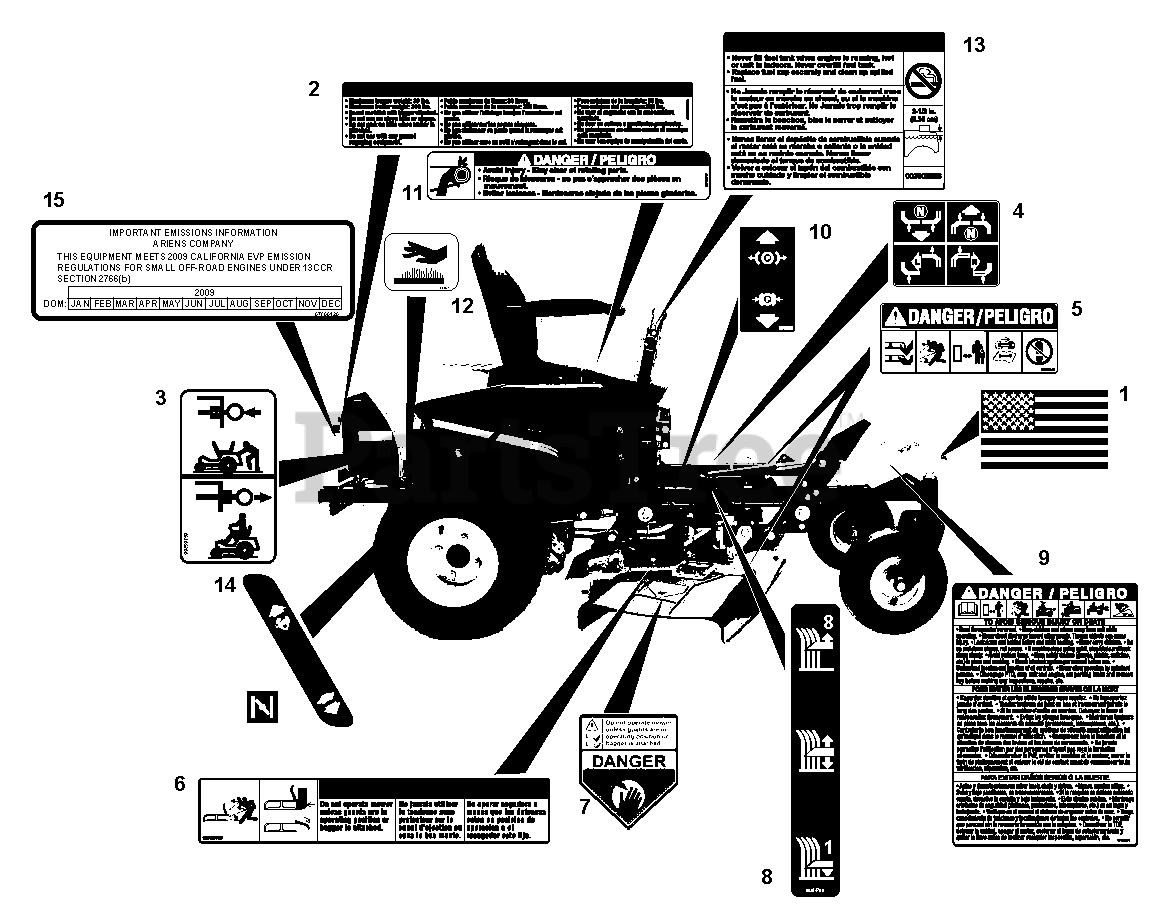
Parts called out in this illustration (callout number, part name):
1	Decal, American Flag
2	Decal, Trailer Hitch
3	Decal, Transmission Disconnect
4	Decal, Instructional Steering
5	Decal, Mower Pan Danger
6	Decal, Warning
7	Decal, CPSC Danger
8	Decal, Cut Height
9	Decal, Bilingual Danger
10	Decal, Parking Brake Lever
11	Decal, Danger
12	Decal, Hot Surface
13	Decal, Fuel Warning
14	Decal, Control
15	Decal, CARB Label (915122)
